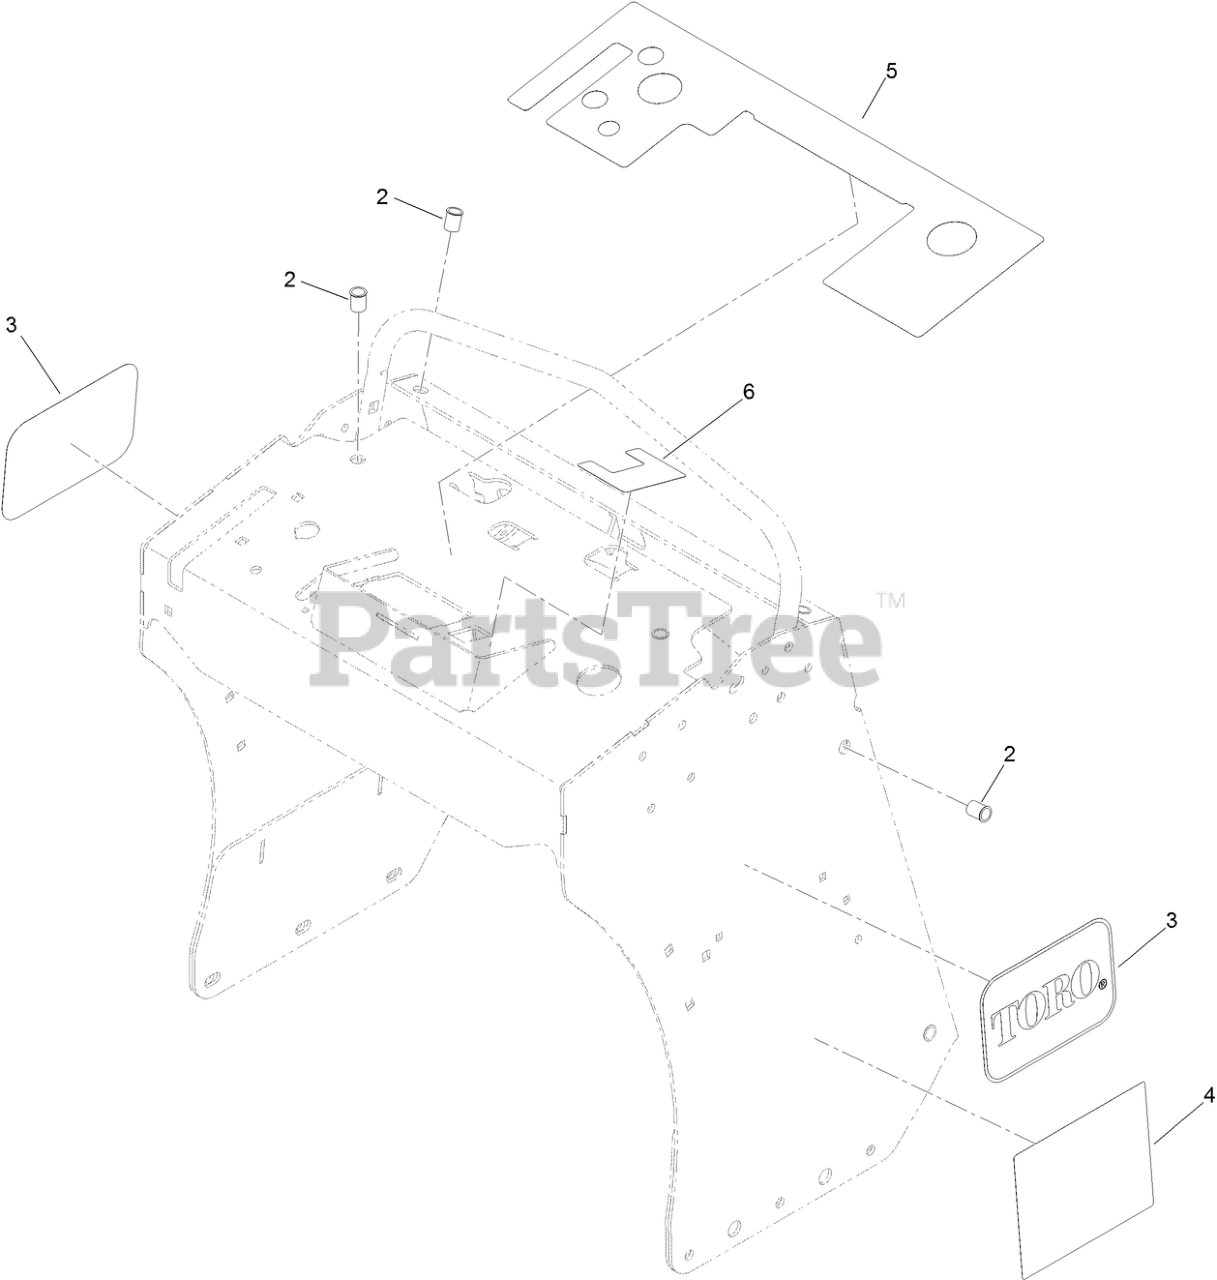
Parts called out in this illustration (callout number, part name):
2	NUT-CLINCH
3	DECAL
4	DECAL-AID, SERVICE
5	DECAL-PANEL, CONTROL
6	DECAL-CONTROL, TINE
